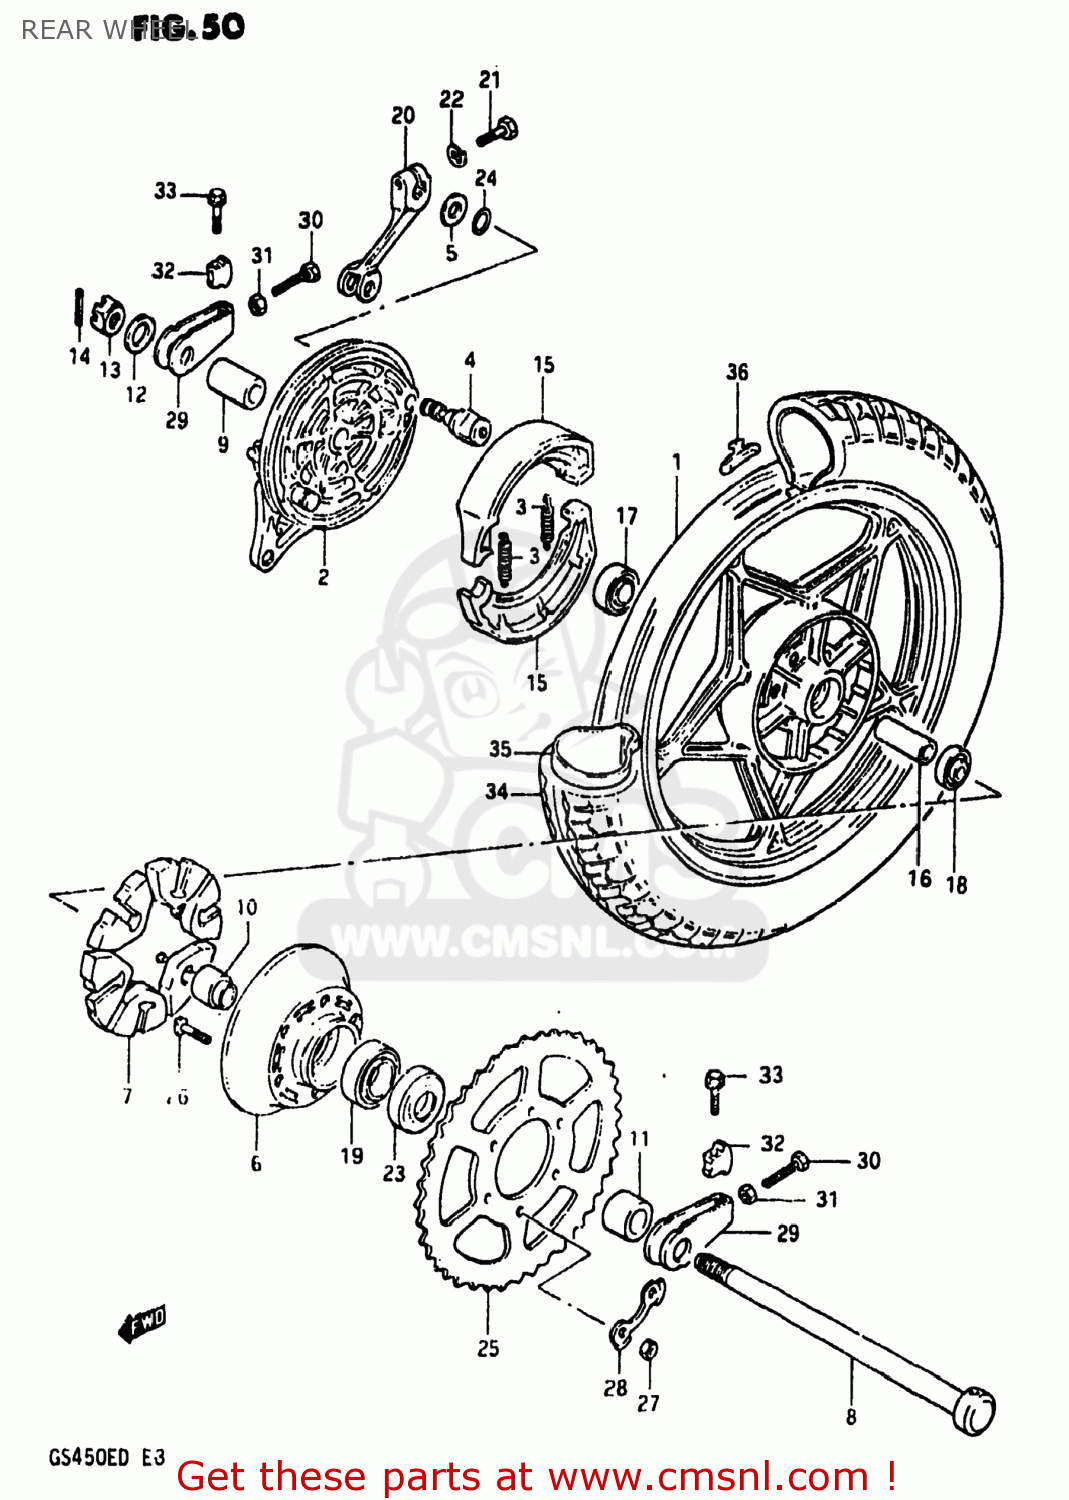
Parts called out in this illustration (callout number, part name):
1	WHEEL,REAR
2	PANEL,REAR HUB
3	SPRING,BRAKE SHOE
4	CAM,FRONT BRAKE
5	WASHER (15X24X1.6)
6	DRUM,REAR SPROCKET MOUNT
7	ABSORBER,RR HUB SHOCK
8	AXLE,REAR
9	SPACER(17.5X28X44.8)
10	SPACER,REAR HUB BEARING
11	SPACER(17X30.5X22.3)
12	WASHER (17X30X3.2)
13	NUT
14	PIN,COTTER
15	SHOE,BRAKE
16	SPACER (17.6X24X57)
17	BEARING
18	BEARING
19	BEARING
20	LEVER,RR BRAKE CAM
21	BOLT
22	LOCK WASHER
23	SEAL,OIL(30.5X52X8)
24	O-RING,BOSS
25	SPROCKET,RR
26	BOLT
27	NUT
28	WASHER
29	ADJUSTER,CHAIN
30	BOLT 8X50
31	NUT
32	SUPPORTER,CHAIN ADJUST
33	BOLT
34	TIRE
35	TUBE ASSEMBLY,WHEEL,INNER
36	BALANCER,WHEEL
